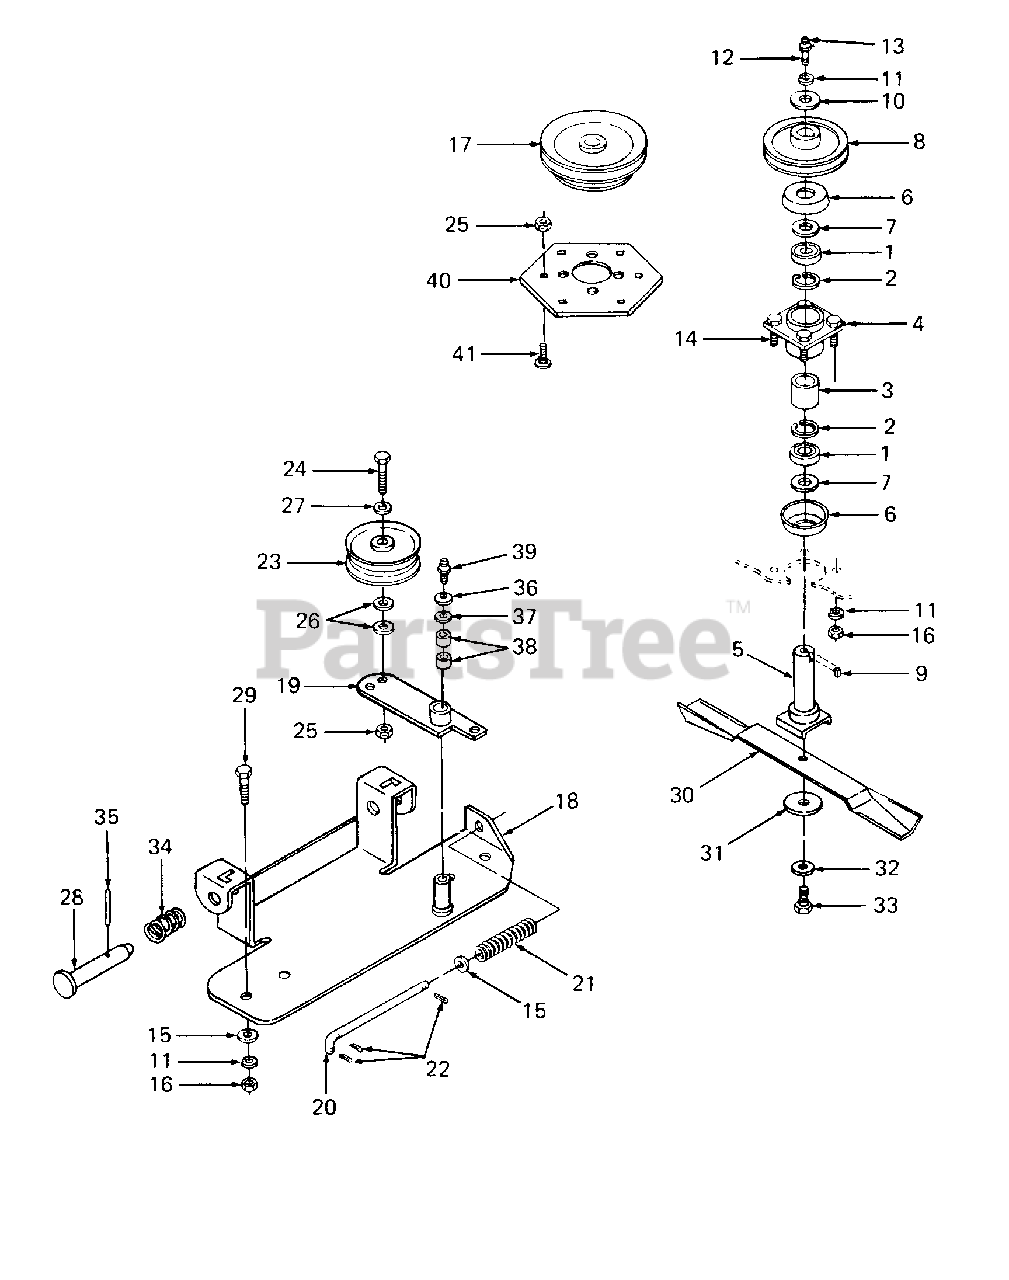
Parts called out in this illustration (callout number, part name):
1	Bearing
2	Ring, Internal Snap
3	Spacer, Bearing
4	Housing, Spindle w/o Bolts
5	Shaft, Spindle
6	Cup, Bearing
7	Washer
8	Pulley, Outer
9	Key, 1/4 X 1 Sq Parallel
11	Washer, Lock, 1/2
12	Bolt Assy
13	Fitting, Grease
14	Bolt, Full Thread Rd Hd, 1/2-13
15	Washer, Flat, .510 ID X 1.00 OD X .060 Thk
16	Nut, Hex, 1/2-13
17	Pulley, Center
18	Plate, Idler
19	Arm, Idler
20	Rod, Idler Spring
21	Spring, Idler
22	Pin, Cotter, 1/8 Dia X 1.25 Lg
23	Pulley, Idler
24	Screw, Hex Cap, 3/8-16 X 2 Lg GR5
25	Nut, Hex Center Lock, 3/8-16
26	Washer, Flat, .438 ID X 1.00 OD X .064 Thk
27	Washer, Lock, 3/8
28	Pin, Quick Latch
29	Bolt, Hex Hd, 1/2-13 X 1.25 Lg GR5
30	Blade, Mower, 21.00 Lg
31	Washer, Mower Blade
32	Washer, Spring
33	Screw, Hex Cap, 1/2-20 X 1.75 Lg GR5
34	Spring, Coupler
35	Pin, Roll, 7/16 X 2
36	Washer, Spring
37	Washer, Flat, .438 ID X 1.00 OD X .064 Thk
38	Bushing, Oilite
39	Fitting, Grease
40	Plate, Spindle Support
41	Bolt, Carriage, 3/8-16 X .75 Lg
